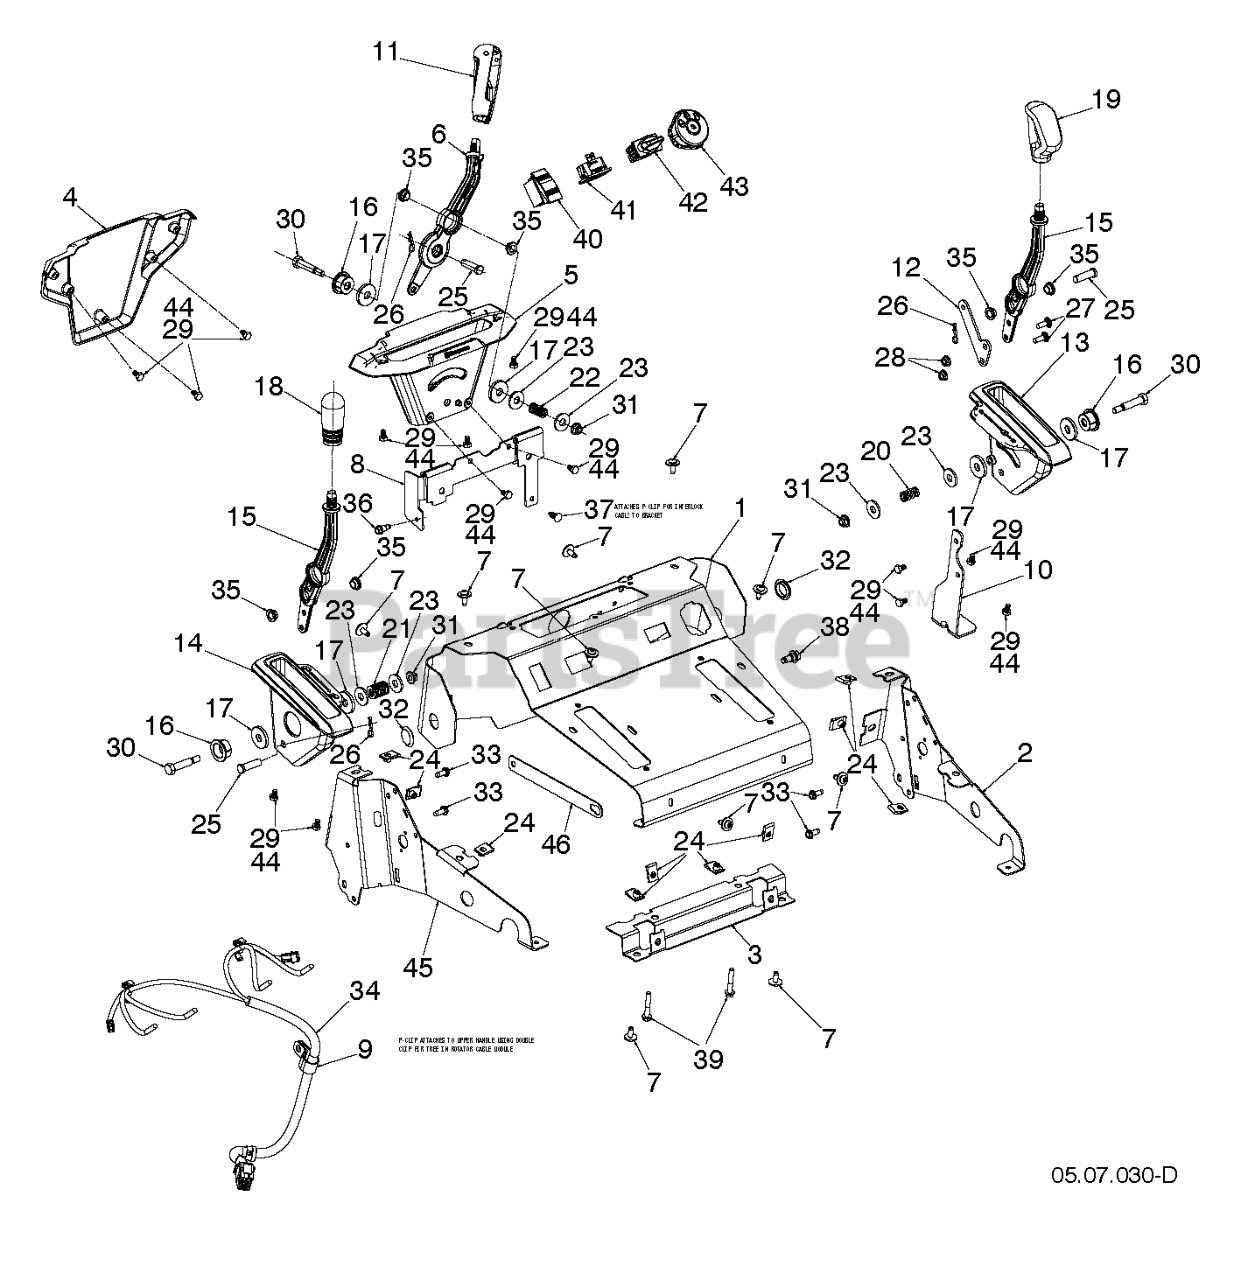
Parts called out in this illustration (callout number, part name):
6	LEVER CHUTE ROTATOR 400S CHUTE
9	CLIP.CABLE.BLK
24	NUT.U-CHNL.1/4-20.550DP.350PNL
26	HAIRPIN.SOFT.ZINC.059X1.125
27	BOLT CUP HEAD SQUARE NECK BOLT
28	NUT.HEX.FLANGE.1/4
31	NUT HEXAGON FLANGE 5/16-18 ST
33	SCREW 14-20 X 5/8
36	BOLT SHOULDER_1/4-20_TRILOB
37	FASTENER.PUSH.O.250X0.783
38	SHOULDER BOLT 5/16-18TT
39	SCREW.HEXCAP.1/4X-20X1.500
40	SWITCH HEATED GRIP BLK
41	HOUR METER SNAPIN, RECTANGULAR
42	SWITCH 3 POSITION ROTARY
43	SWITCH IGNITION 3 POSITION 6-W
